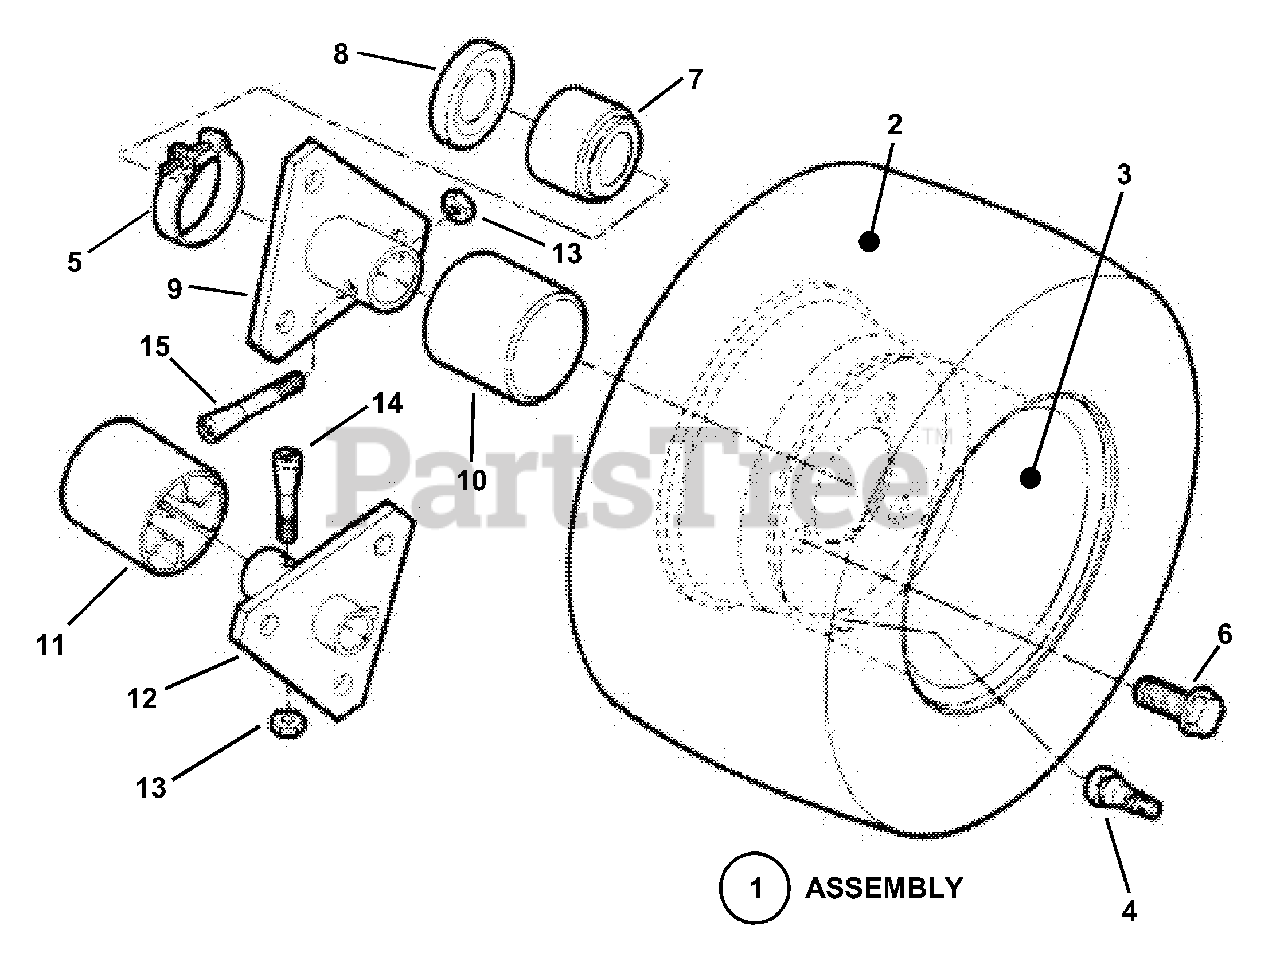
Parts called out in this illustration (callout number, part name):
1	ASSEMBLY, Rear Tire & Rim
2	TIRE, 16-6.50 x 8
3	RIM, Extra Wide
4	VALVE, Air (Snap-in)
5	CLAMP, Right Hand (8, 10 & 13 HP)
6	BOLT, 1/2-20 x 3/4" Lug (6)
7	BOOT, Right Hand (8 & 10 HP)
8	SEAL, Oil
9	HUB, Rear Wheel R. H. (Weldment)
10	CAP, Hub
11	CAP, Hub (Left Hand)
12	HUB, Rear Wheel L.H. (Weldment)
13	NUT, 5/16-24 Hex Center Lock
14	BOLT, 5/16-24 x 1-5/8" Tapered (Left Hand)
15	BOLT, 5/16-24 x 2" Tapered (Right Hand)
